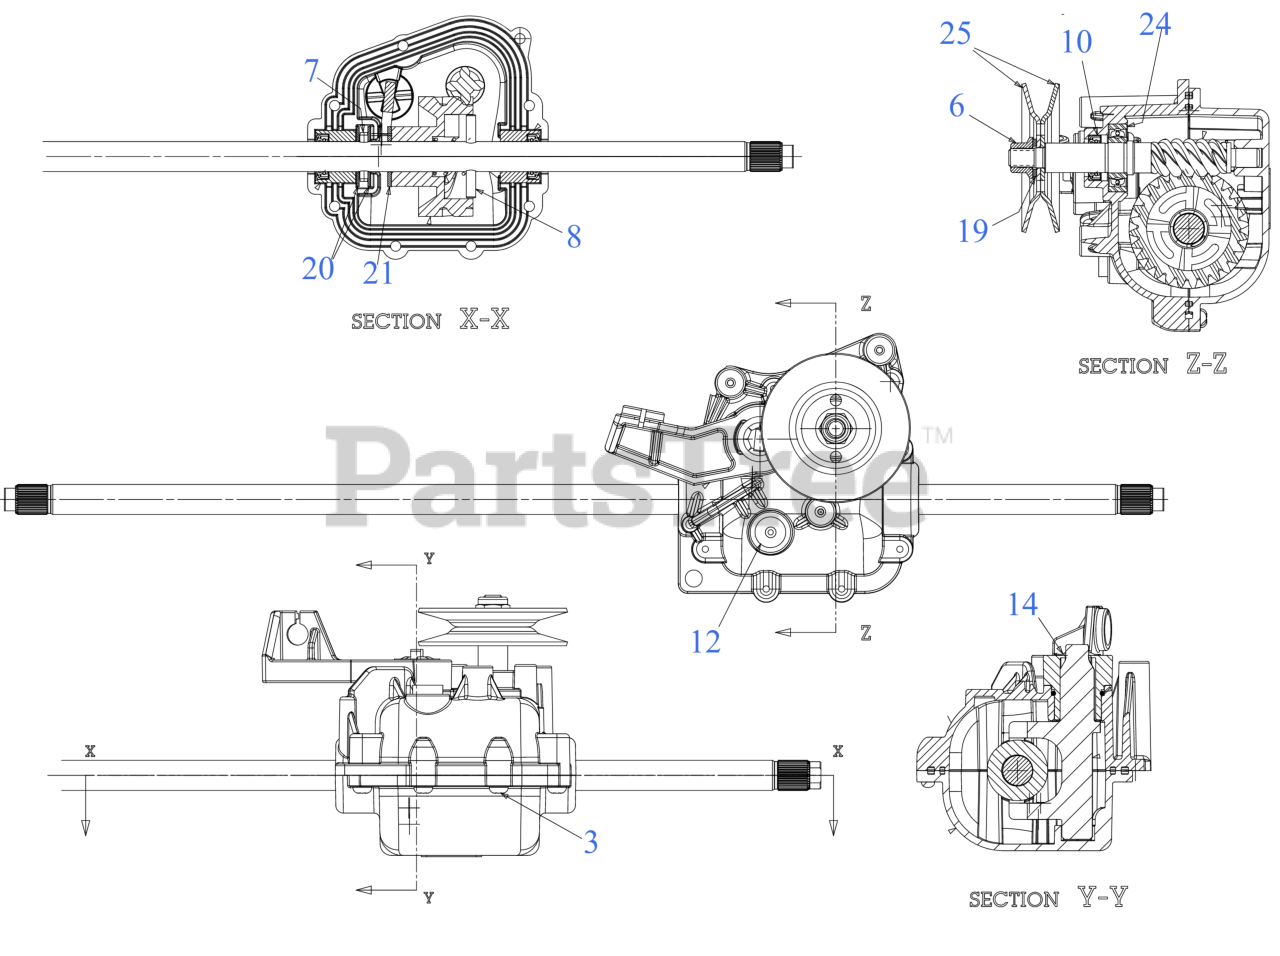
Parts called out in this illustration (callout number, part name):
3	SCREW .159 x .610
6	FLANGE LOCK NUT 5/16-18
7	SPRING PIN1/8 x .812
12	RUBBER PLUG
19	FLAT WASHER
20	FLAT WASHER .508X1.000X.040
21	FLAT WASHER .510 x .995
24	BALL BEARING
25	PULLEY HALF SHEAVE
